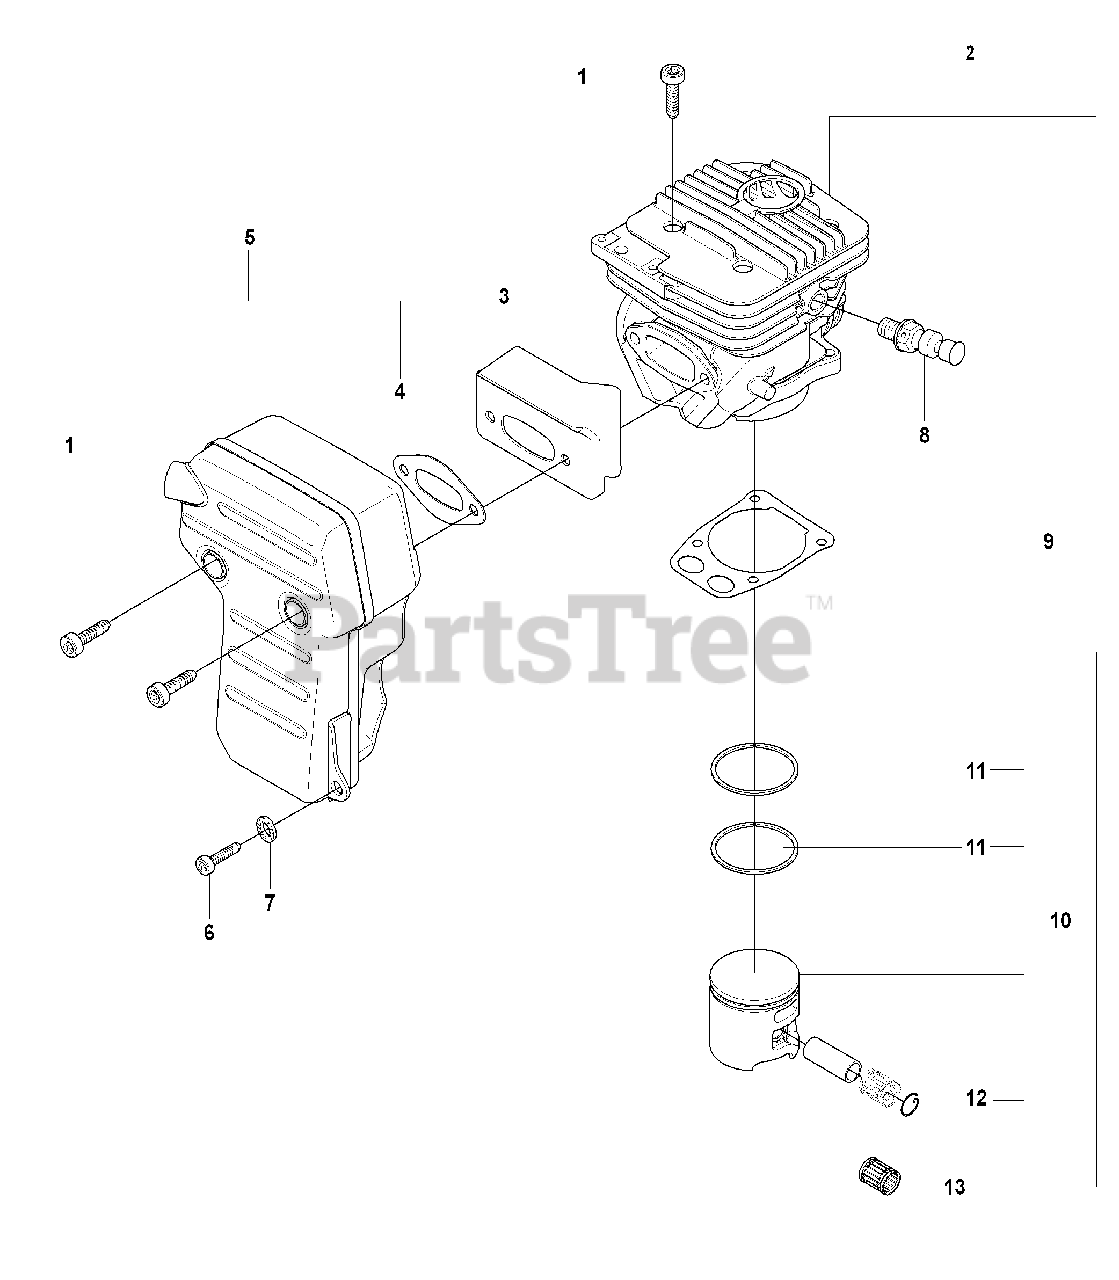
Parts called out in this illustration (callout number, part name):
2	CYLINDER ASSY
3	HEAT DEFLECTOR
4	GASKET MUFFLER
5	MUFFLER
8	DECOMPRESSION VALVE
9	GASKET
10	PISTON
11	PISTON RING
13	NEEDLE BEARING
